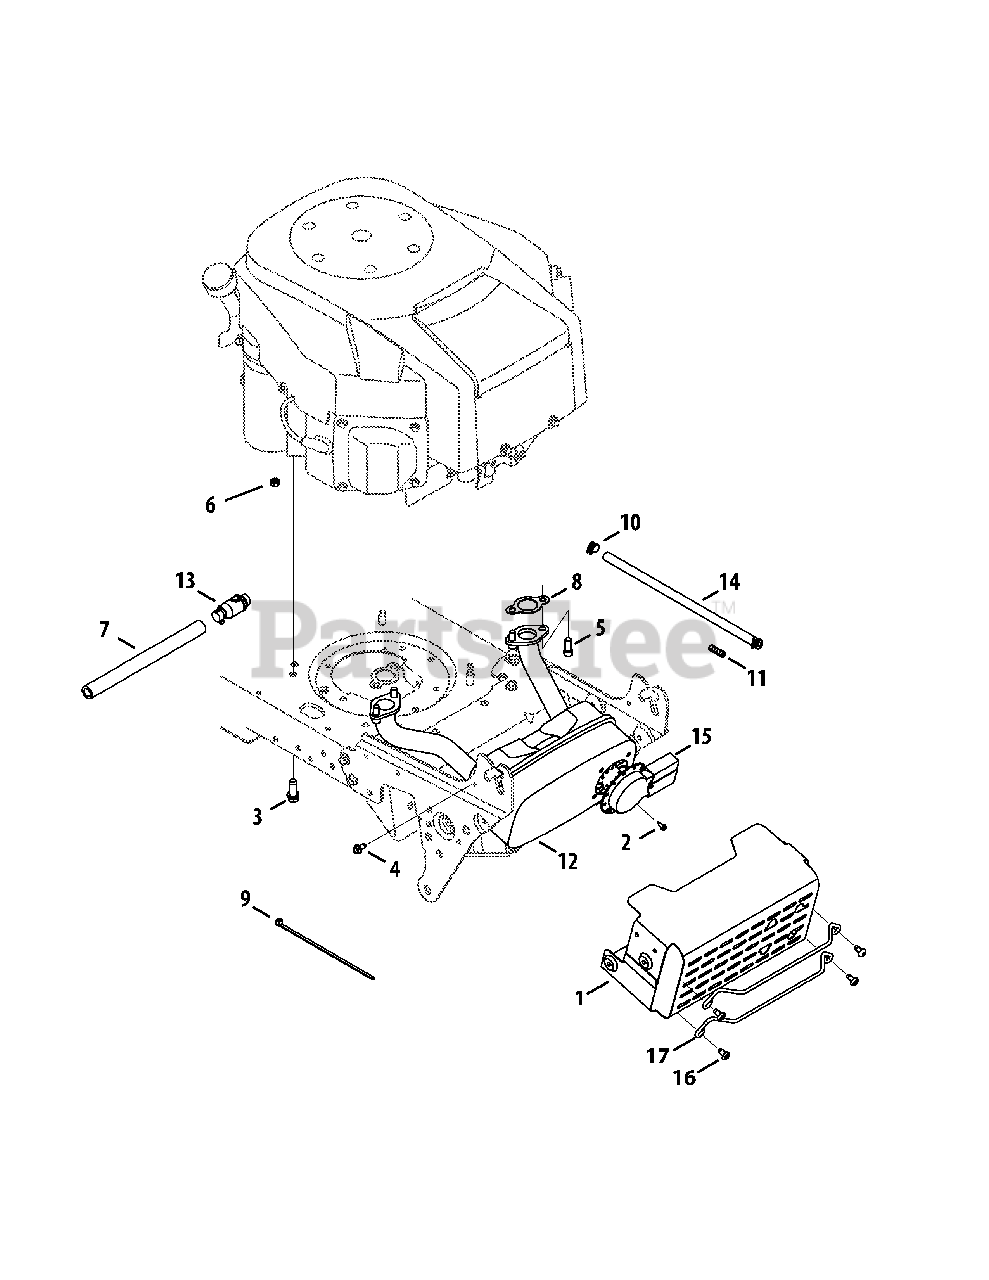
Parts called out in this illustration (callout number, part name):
1	Shield Ass’y, Muffler
2	Screw, Ab, #8-18, 0.500,
3	Screw, Self-tapping, 3/8-16, 1.000,
4	Screw, Self-tapping, 1/4-20, 0.500,
5	Screw, Socket Head, 5/16-18, .750
6	Nut, Sems, 1/4-20
7	Hose, Extension, Oil Drain
8	Gasket, Exhaust,Kohler
9	Cable, Tie, 3/16 x .05 x 7.4
10	Clamp, Hose, .490 Dia.
11	Vent Hose
12	Muffler, Kohler Twin
13	Drain, Oil
14	Hose, Fuel, Low Permeation, 1/4
15	Muffler Deflector Long
16	Pan Torx Screw 1/4
17	Muffler Guard Rod
